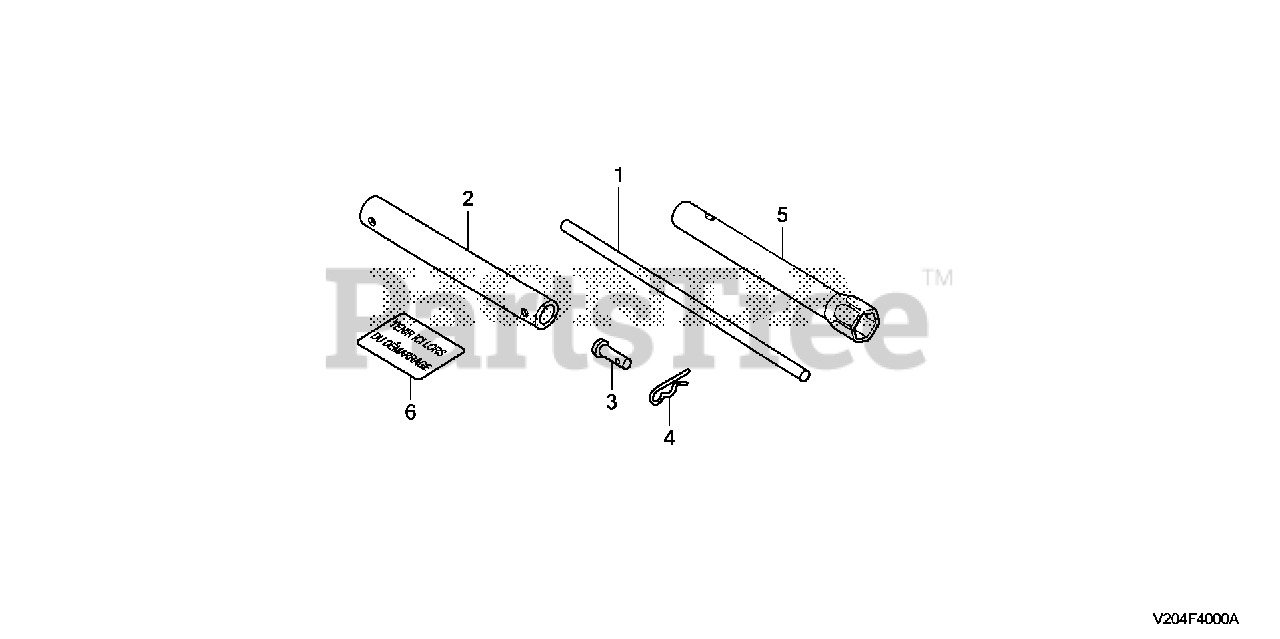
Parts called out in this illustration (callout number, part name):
1	HANDLE, BOX WRENCH
2	PIPE, BOX WRENCH EXTENSION
3	PIN, ROLLER ARM (8X22)
4	PIN, LOCK (8MM)
5	WRENCH, BOX (P21)
